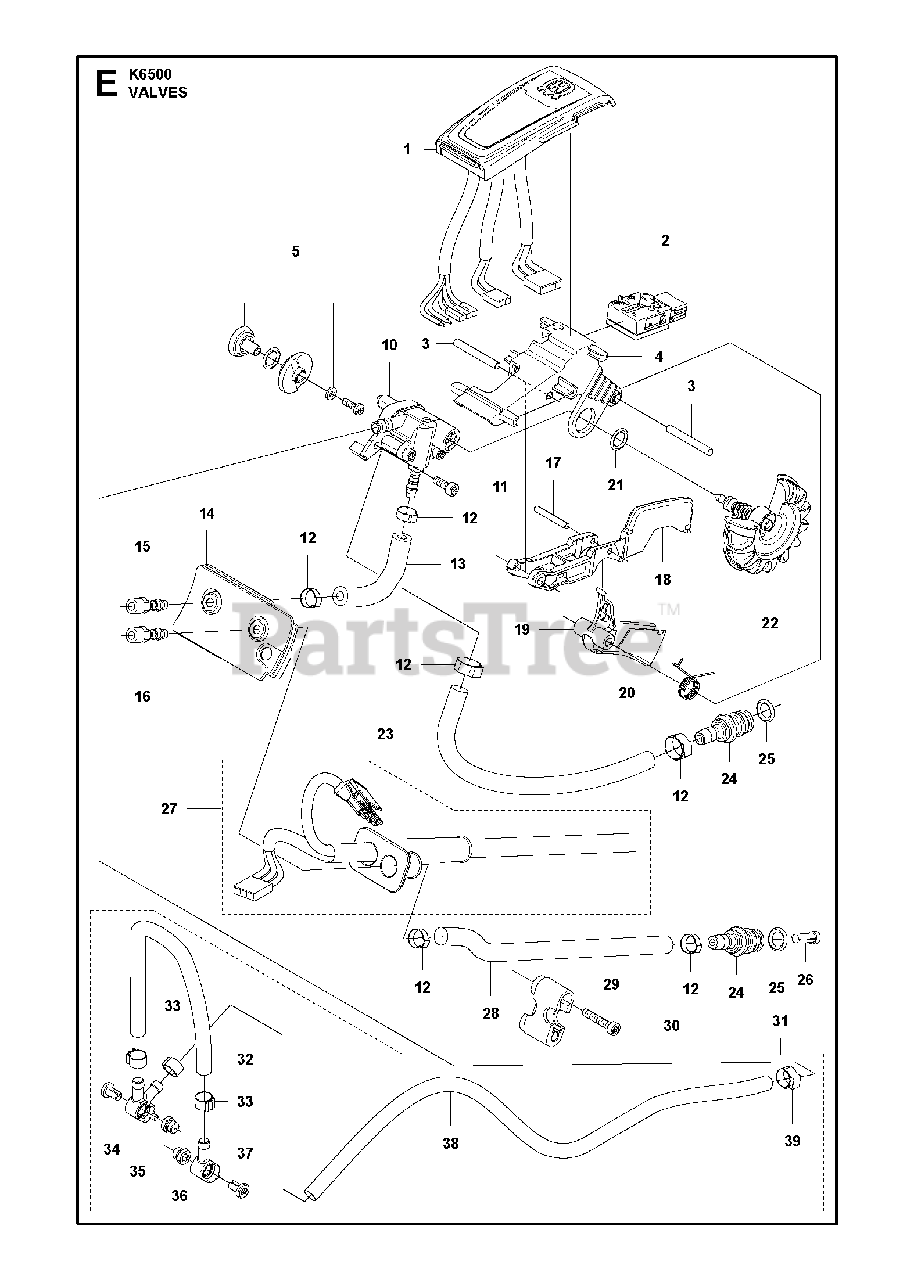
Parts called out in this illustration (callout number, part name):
3	PARALLEL PIN
11	SCREW ITXSCT
17	PARALLEL PIN
30	SCREW ITXSCT
34	SCREW ITXSCM
